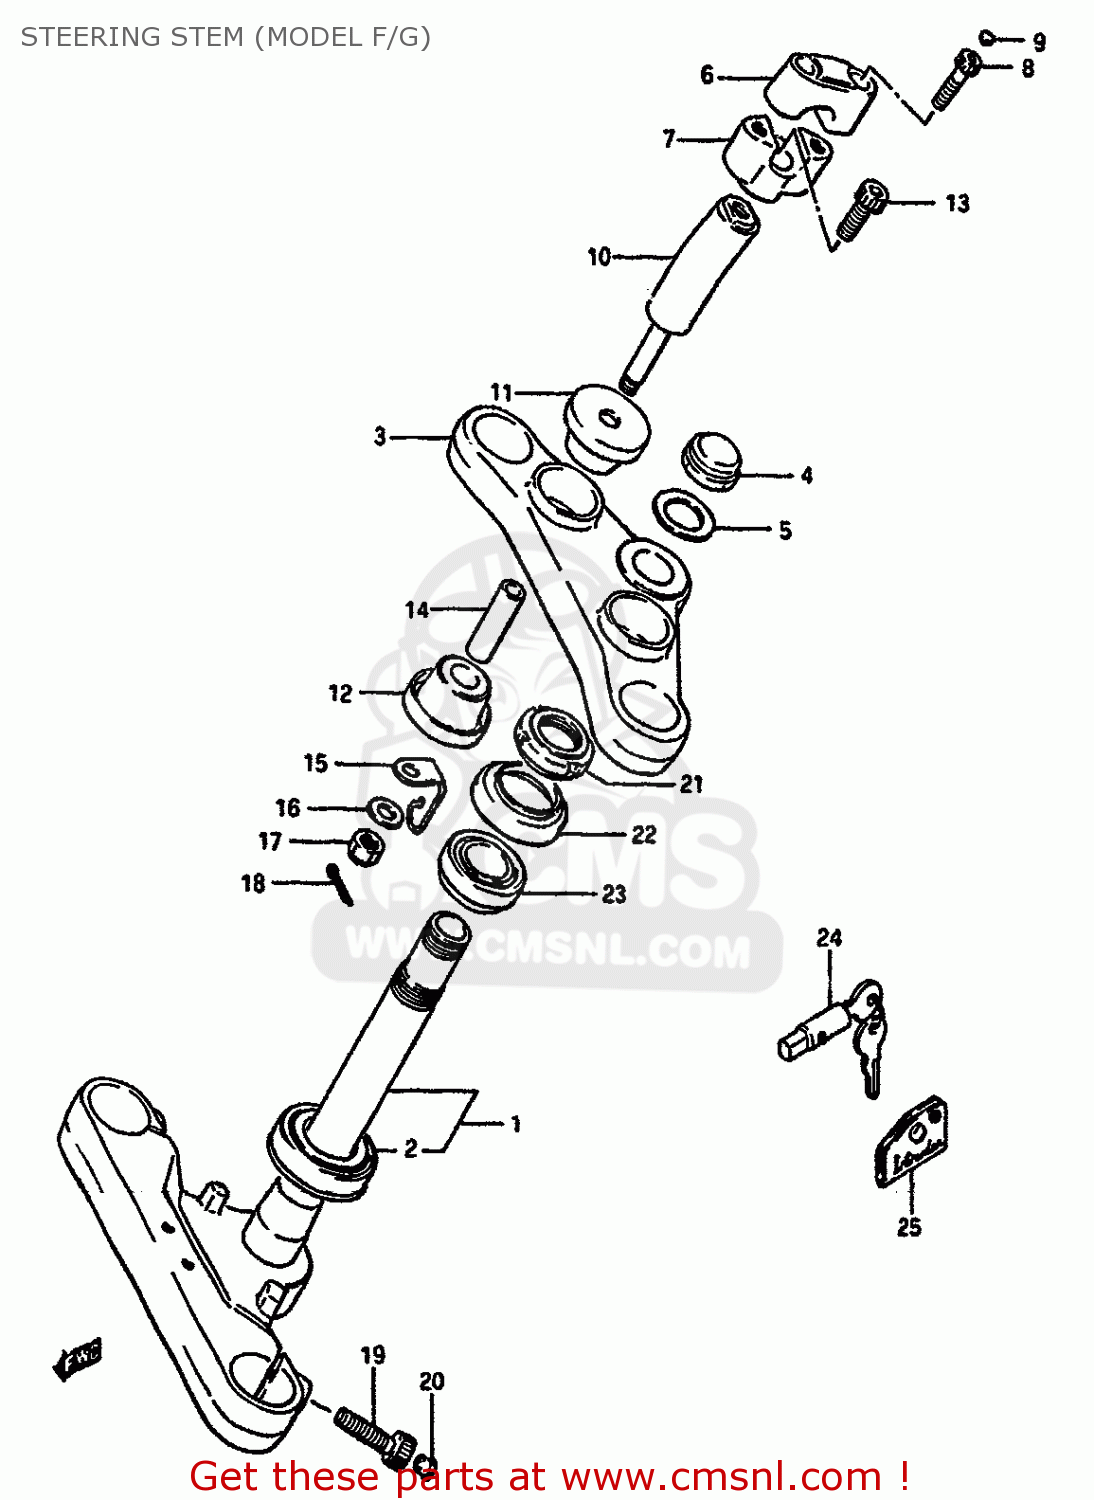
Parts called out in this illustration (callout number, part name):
1	STEM,STEERING
2	BEARING
3	HEAD,STEERING STEM
4	NUT,STEM HEAD
5	WASHER
6	HOLDER,HANDLEBAR
7	HOLDER,HANDLEBAR
8	BOLT, REAR (8X30)
9	CAP(OD:14.5)
10	STAY,HANDLE
11	CUSHION
12	CUSHION,LWR
13	BOLT
14	SPACER(10.2X14X46)
15	CLAMP,SPEEDOMETER CABLE
16	WASHER 10MM
17	NUT
18	PIN 20X20
19	BOLT,STEERING STEM HEAD
20	CAP(OD:12)
21	NUT,STEERING STEM(25X44X10)
22	DUST SEAL,STEERING,UPPER
23	TAPER,ROLLER BEARING
24	LOCK ASSEMBLY,STEERING (NEI
25	CASE,STEERING KEY
